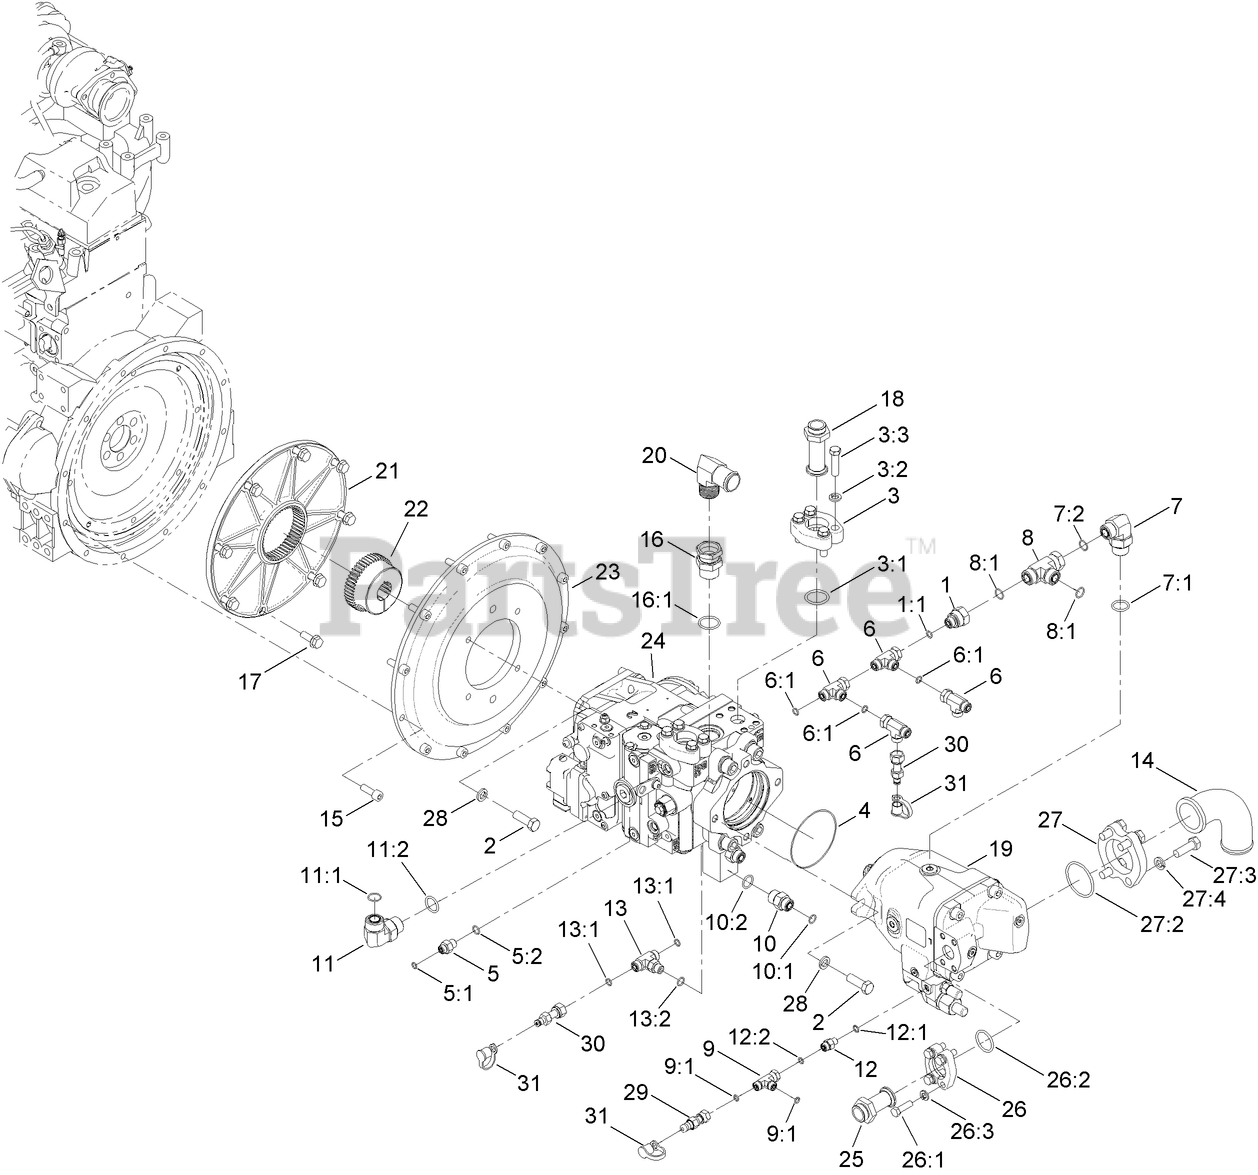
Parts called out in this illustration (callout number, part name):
1	FITTING-HYD
1:1	O-RING
2	SCREW-HH
3	HYD FLANGE KIT
3:1	O-RING
3:2	WASHER-LOCK
3:3	SCREW-HH
4	O-RING
5	FITTING-STRAIGHT
5:1	O-RING
5:2	O-RING
6	FITTING-TEE, SWIVEL NUT
6:1	O-RING
7	FITTING-ELBOW 90
7:1	O-RING
7:2	O-RING
8	FITTING-HYD, TEE
8:1	O-RING
9	FITTING-HYD
9:1	O-Ring
10	FITTING-STRAIGHT
10:1	O-RING
10:2	O-RING
11	FITTING-ELBOW-90
11:1	O-RING
11:2	O-RING
12	FITTING-STRAIGHT
12:1	O-RING
12:2	O-RING
13	ADAPTER
13:1	O-RING
13:2	O-RING
14	END-HOSE
15	SCREW-HSH
16	FITTING-STRAIGHT
16:1	O-RING
17	SCREW-HHF
18	ADAPTER-FLANGE, STRAIGHT
19	HYD LOAD SENSE PISTON PUMP ASM
20	FITTING-ELBOW, 90
21	COUPLING-DRIVE
22	HUB-STEEL
23	COVER-FLYWHEEL, PUMP MOUNT
24	HYD HYDROSTAT PUMP ASM
25	ADAPTER-FLANGE, STRAIGHT
26	SPLIT FLANGE KIT
26:1	SCREW-HH
26:2	O-RING
26:3	WASHER-LOCK
27	FLANGE KIT
27:2	O-RING
27:3	SCREW-HH
27:4	WASHER-LOCK
28	WASHER-LOCK
29	NIPPLE-TEST
30	NIPPLE-TEST
31	CAP-DUST
